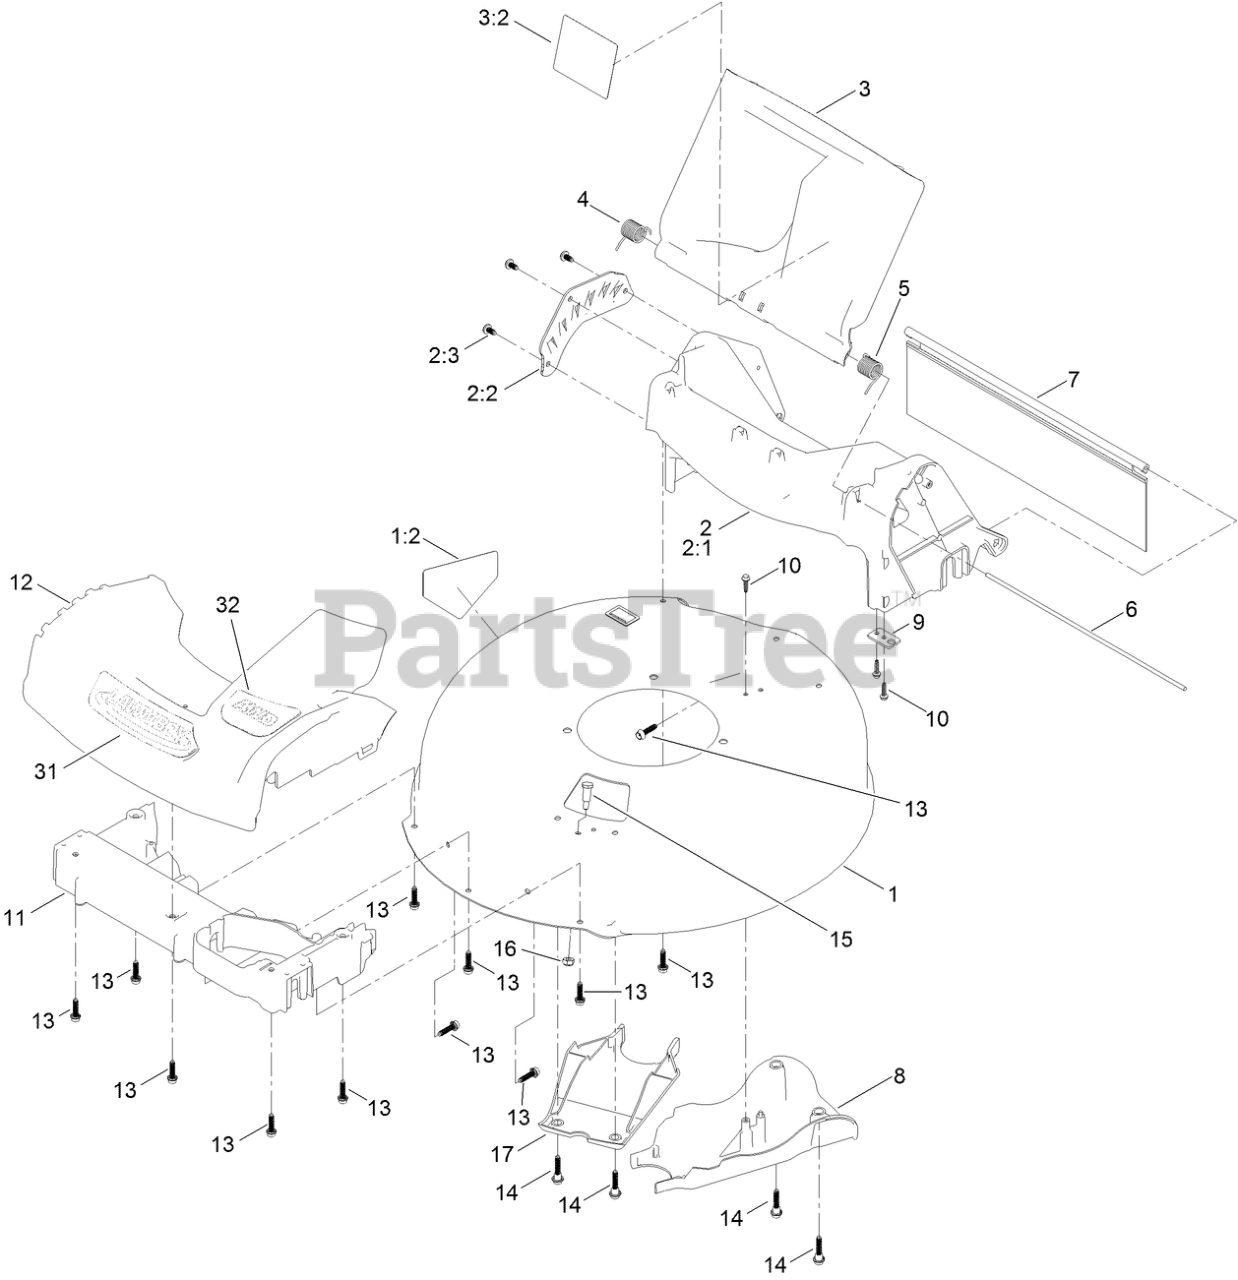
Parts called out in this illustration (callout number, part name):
1	HOUSING ASM
1:2	DECAL-DANGER
2	CHUTE ASM
2:1	CHUTE
2:3	SCREW-PLASTIC TPH
3	REAR DEFLECTOR ASM
3:2	DECAL-WARNING
4	SPRING-TORSION
5	SPRING-TORSION
7	SHIELD-TRAILING
8	COVER-BELT
9	BRACKET-CABLE
10	SCREW-HWH
11	MOUNT-BUMPER
13	SCREW-FLANGE, PLASTIC
14	SCREW-SHOULDER, HHF
15	BOLT-SHOULDER
16	NUT-LOCK, NI
17	COVER-BELT, FRONT
31	DECAL-DECK
32	DECAL-COVER
